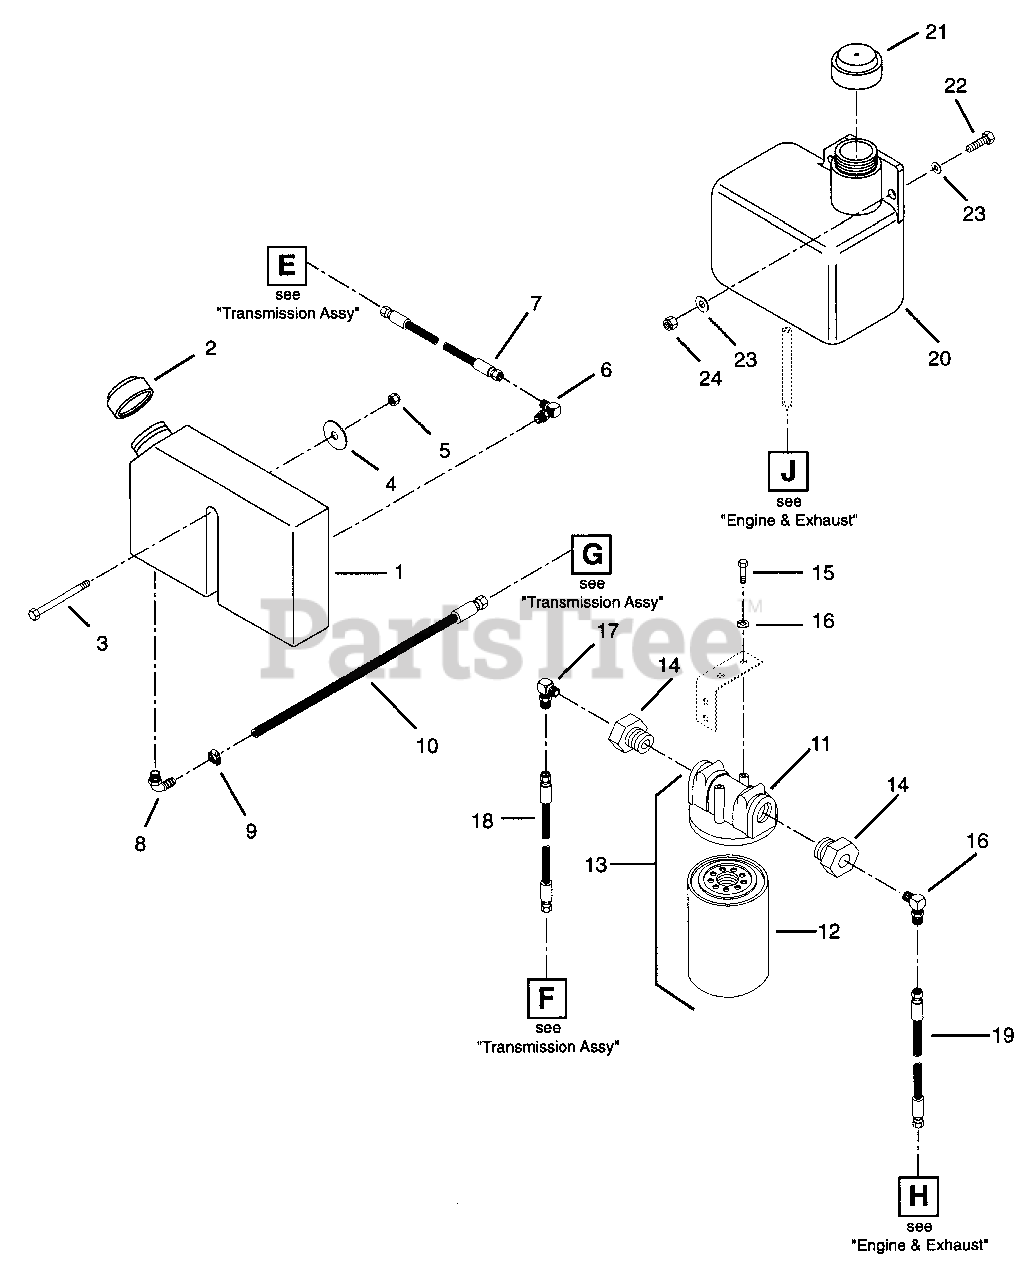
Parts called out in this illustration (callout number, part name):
1	Tank,Hydraulic
2	Cap,Tank
3	Bolt-Hex .31-18 x 3.50
4	Washer,Flat .344 x 3.0 x .060
5	Nut-Locking-Nylon .312-18 Grade 2
6	Adapter,Fitting 90 deg.
7	Assembly,Hydraulic Hose
8	Fitting-Elbow .50 x .50
9	Clamp, .88 Diameter Hose
10	Hose Assembly
11	Head,Oil Filter
12	Replacement Element
13	Assembly,Filter
14	Adapter-Hydraulic .88-14
15	Bolt-Hex .25-20 x .63
16	Washer-Lock .250 Reg.
17	Adapter
18	Assembly,Hydraulic Hose
19	Assembly,Hydraulic Hose
20	Tank,Plastic 1.5 Qt.
21	Cap, 1-5/8 Vented
22	Bolt-Hex .31-18 x .75 Grade 5
23	Washer-Flat-Steel .344 x .688 x .065
24	Nut-Hex .312-18 Zinc Grade 2
